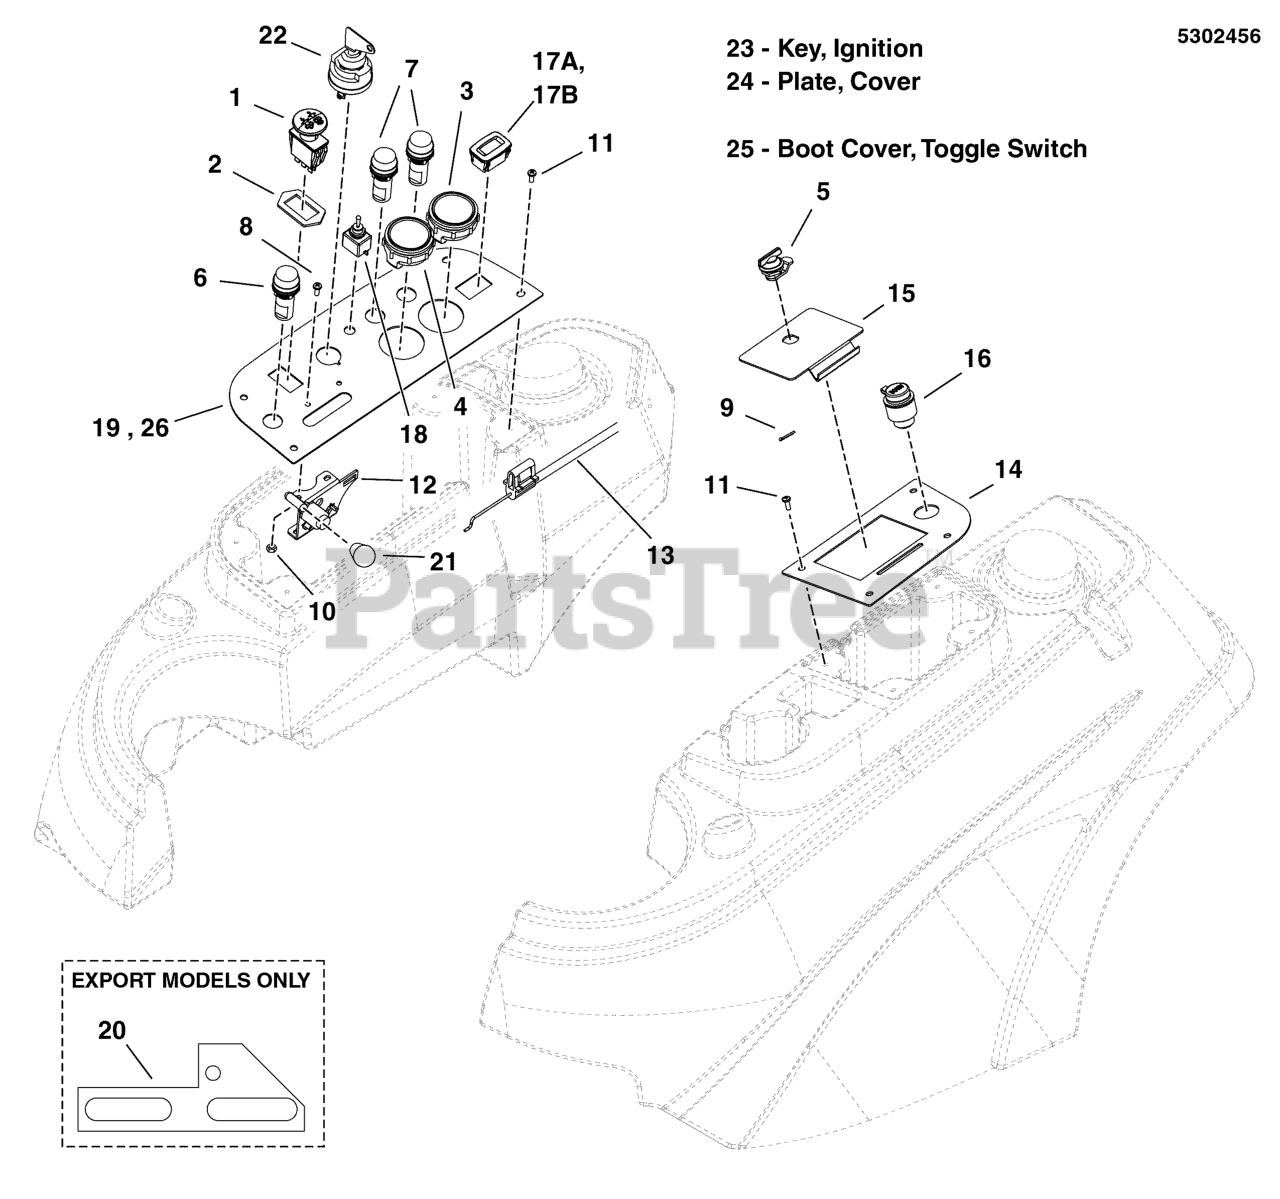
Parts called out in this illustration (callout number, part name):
1	SWITCH, BLADE ENGAGEMENT
2	RING, SWITCH RETAINER
3	VOLTMETER, UNLIT, 12V, W/ COLOR GRAPHIC
4	GAUGE, WATER TEMPERATURE
5	LATCH, CONTROL PANEL
6	LIGHT, GLOW PLUG, 22MM AMBER
7	LIGHT, WARNING, 22MM RED
8	SCREW- #10-24 X 1/2 ROUND PHILLIPS
9	PIN, 3/32 X 0.750, COT, ZINC/CLEAR
10	NUT, #10-24 HEX NYLON LOCK
11	SCREW, 1/4-20 X 1/2 ALLEN BH
12	HANDLE, THROTTLE CONTROL
14	PANEL, CONTROL - LH
15	COVER, CONTROL PANEL
16	POWER, OUTLET - 12 VOLT
18	SWITCH, TOGGLE
19	CONTROL PANEL, IS5100Z RH - BLK
20	PLATE, THROTTLE STOP
21	THROTTLE CONTROL HANDLE/KNOB
22	SWITCH-IGNITION (COMPLETE)
25	BOOT COVER, TOGGLE SWITCH
26	CONTROL PANEL, IS5000Z, RH - BLK
